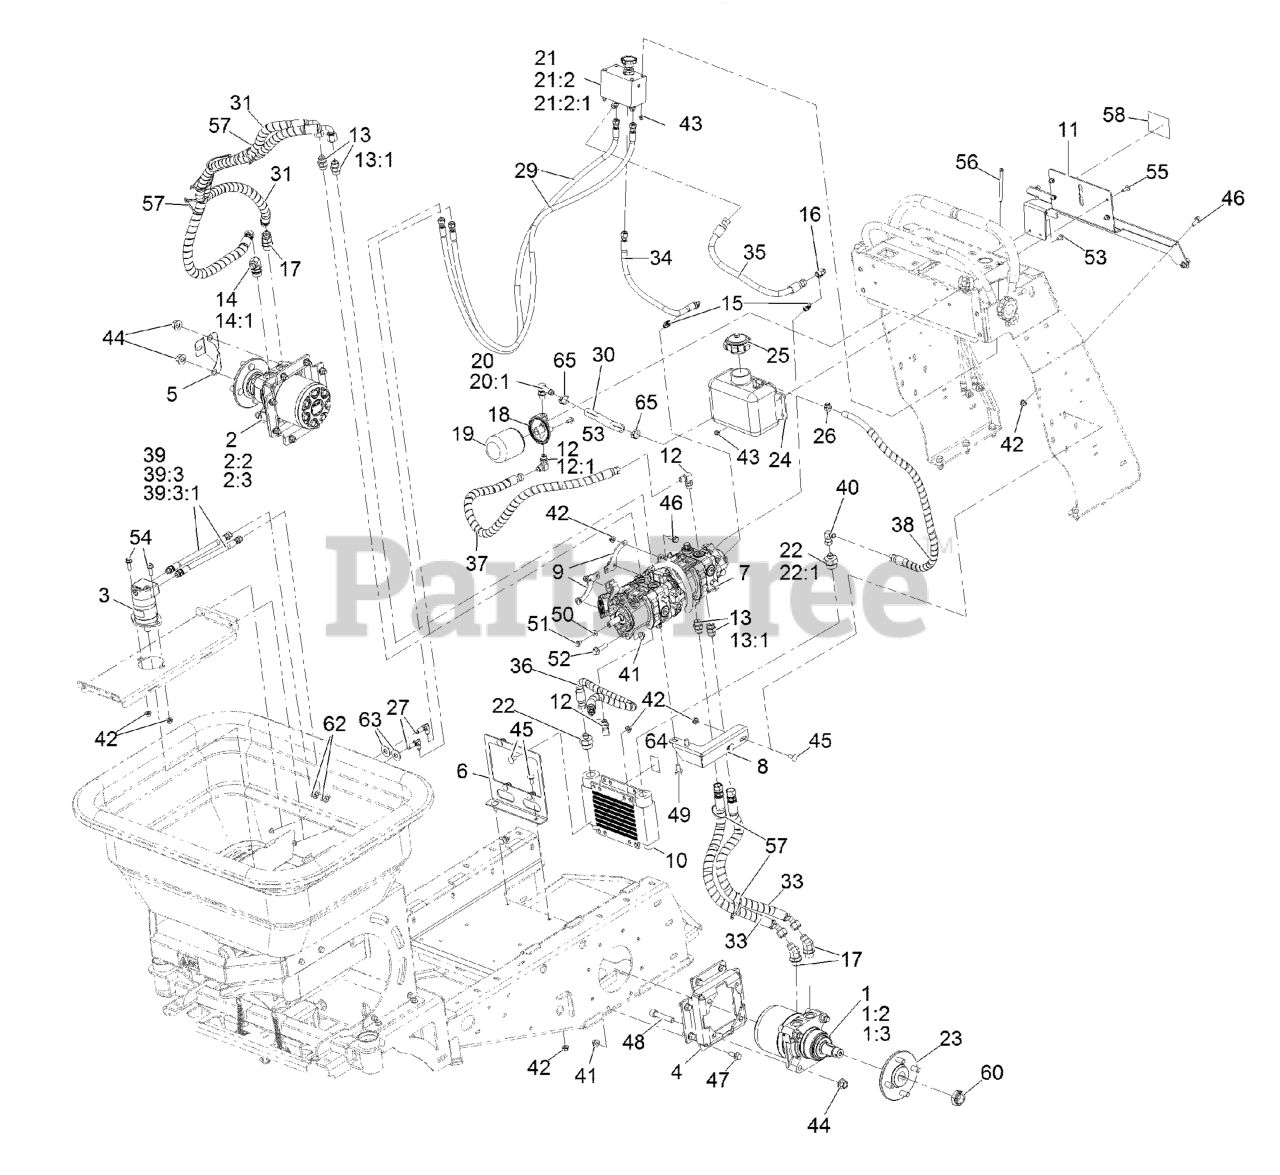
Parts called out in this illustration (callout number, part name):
1	MOTOR, LH WHEEL
1:2	KEY-WOODRUFF
1:3	SEAL KIT
2	MOTOR, RH WHEEL
2:2	KEY-WOODRUFF
2:3	SEAL KIT
3	MOTOR-HYDRAULIC, SPREADER
4	Mount-Motor, Wheel
5	BRACKET-HOPPER, SPEEDOMET
6	Mount-Cooler
7	PUMP-TANDEM
8	Bracket-Support, Hydro Pump
9	Extension, Hydro Pump
10	COOLER-OIL
11	Mount, Hydraulic Tank And Filter
12	FITTING-ELBOW, 90 DEG
12:1	O-RING
13	FITTING-STRAIGHT
13:1	O-RING
14	FITTING-90 DEG
14:1	O-RING
15	FITTING-STRAIGHT
16	FITTING-90 SWIVEL
17	FITTING-ELBOW, 45 DEG
18	HEAD-FILTER
19	FILTER-HYDRAULIC
20	FITTING-ELBOW, 90
20:1	O-RING
21	MANIFOLD-HOPPER, W/OUT RE
21:2	FITTING-ELBOW, 45 DEG
21:2:1	O-RING
22	ADAPTER-STRAIGHT
22:1	O-RING
23	HUB-WHEEL
24	TANK-HYDRAULIC, PLASTIC
25	Cap-Vented
26	CLAMP-OETIKER, 167
27	FITTING-ELBOW, 90
29	HOSE ASM, HYD HP
30	HOSE-HYDRAULIC
31	HOSE ASM, HYD HP
33	HOSE ASM, HYD HP
34	Hose ASM, HYD HP
35	Hose ASM, HYD LP
36	Hose ASM, HYD LP
37	Hose ASM, HYD LP
38	Hose ASM, HYD LP
39	HOSE ASM, HYD HP
39:3	Fitting-Straight, Rigid
39:3:1	O-RING
40	ELBOW-SWIVEL, 90 DEG
41	Nut-Hex Flange
42	Nut-Hex Flange
43	Nut-Hex Flange
44	Nut-Lock 1/2-13
45	SCREW-CARR
46	SCREW-HHF
47	SCREW-HHF
48	Screw-HSH
49	SCREW-HHF
51	SCREW-HHF
52	SCREW-HHF
53	SCREW-HHF
54	SCREW-HHF
55	Screw-Hsbhf
56	Screw-HSBH
57	TIE-CABLE
58	DECAL-OIL
60	LOCKNUT
62	Nut-Jam
63	Washer-SS, 1.25 OD, .503 ID
64	DECAL-WARNING
65	CLAMP-OETIKER, 167
